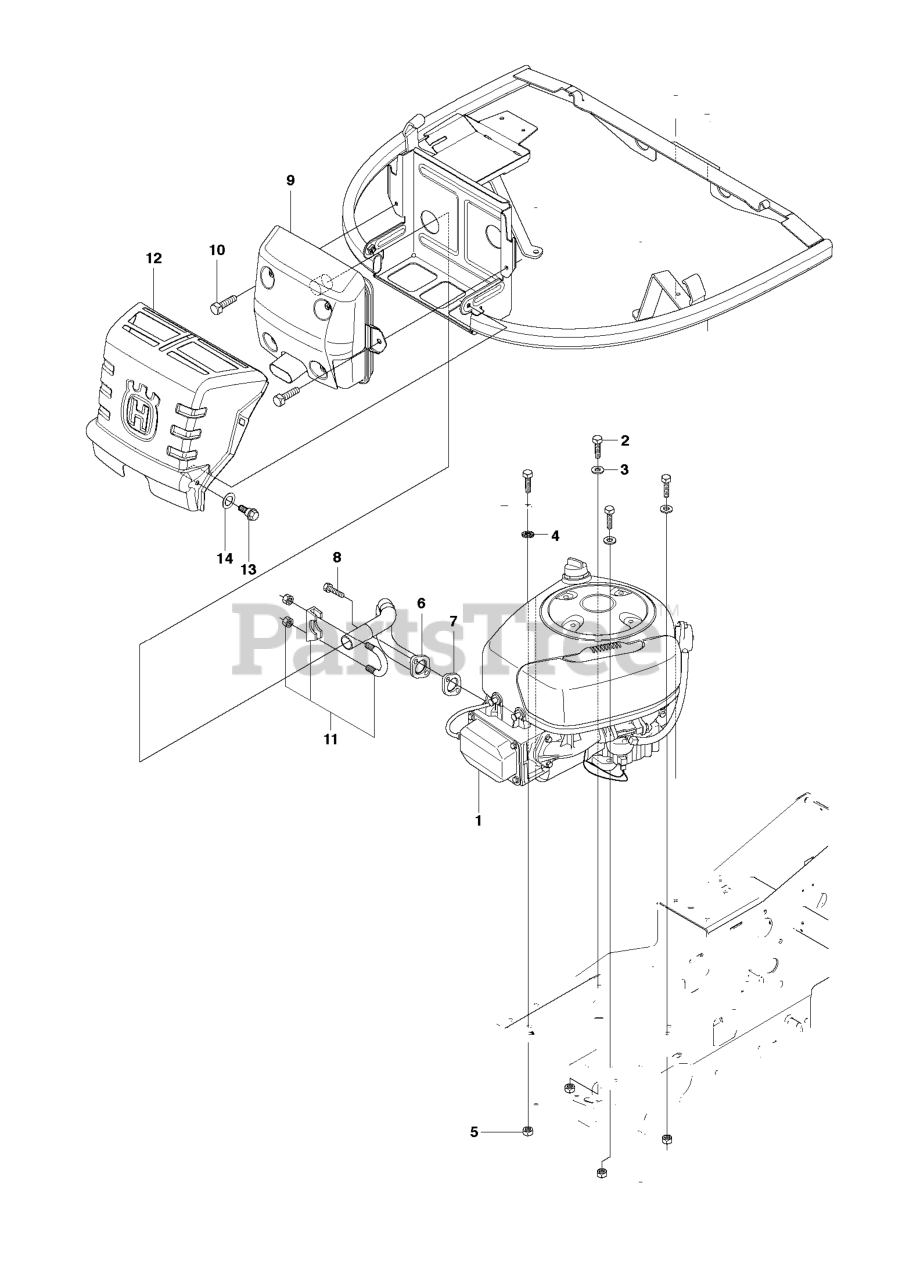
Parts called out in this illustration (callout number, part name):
3	WASHER BRB 8.4X17
5	LOCKNUT M8
6	EXHAUST PIPE ASSY
9	MUFFLER ASSY
11	CLAMP
12	HEAT PROTECTOR
14	SPRINGWASHER
